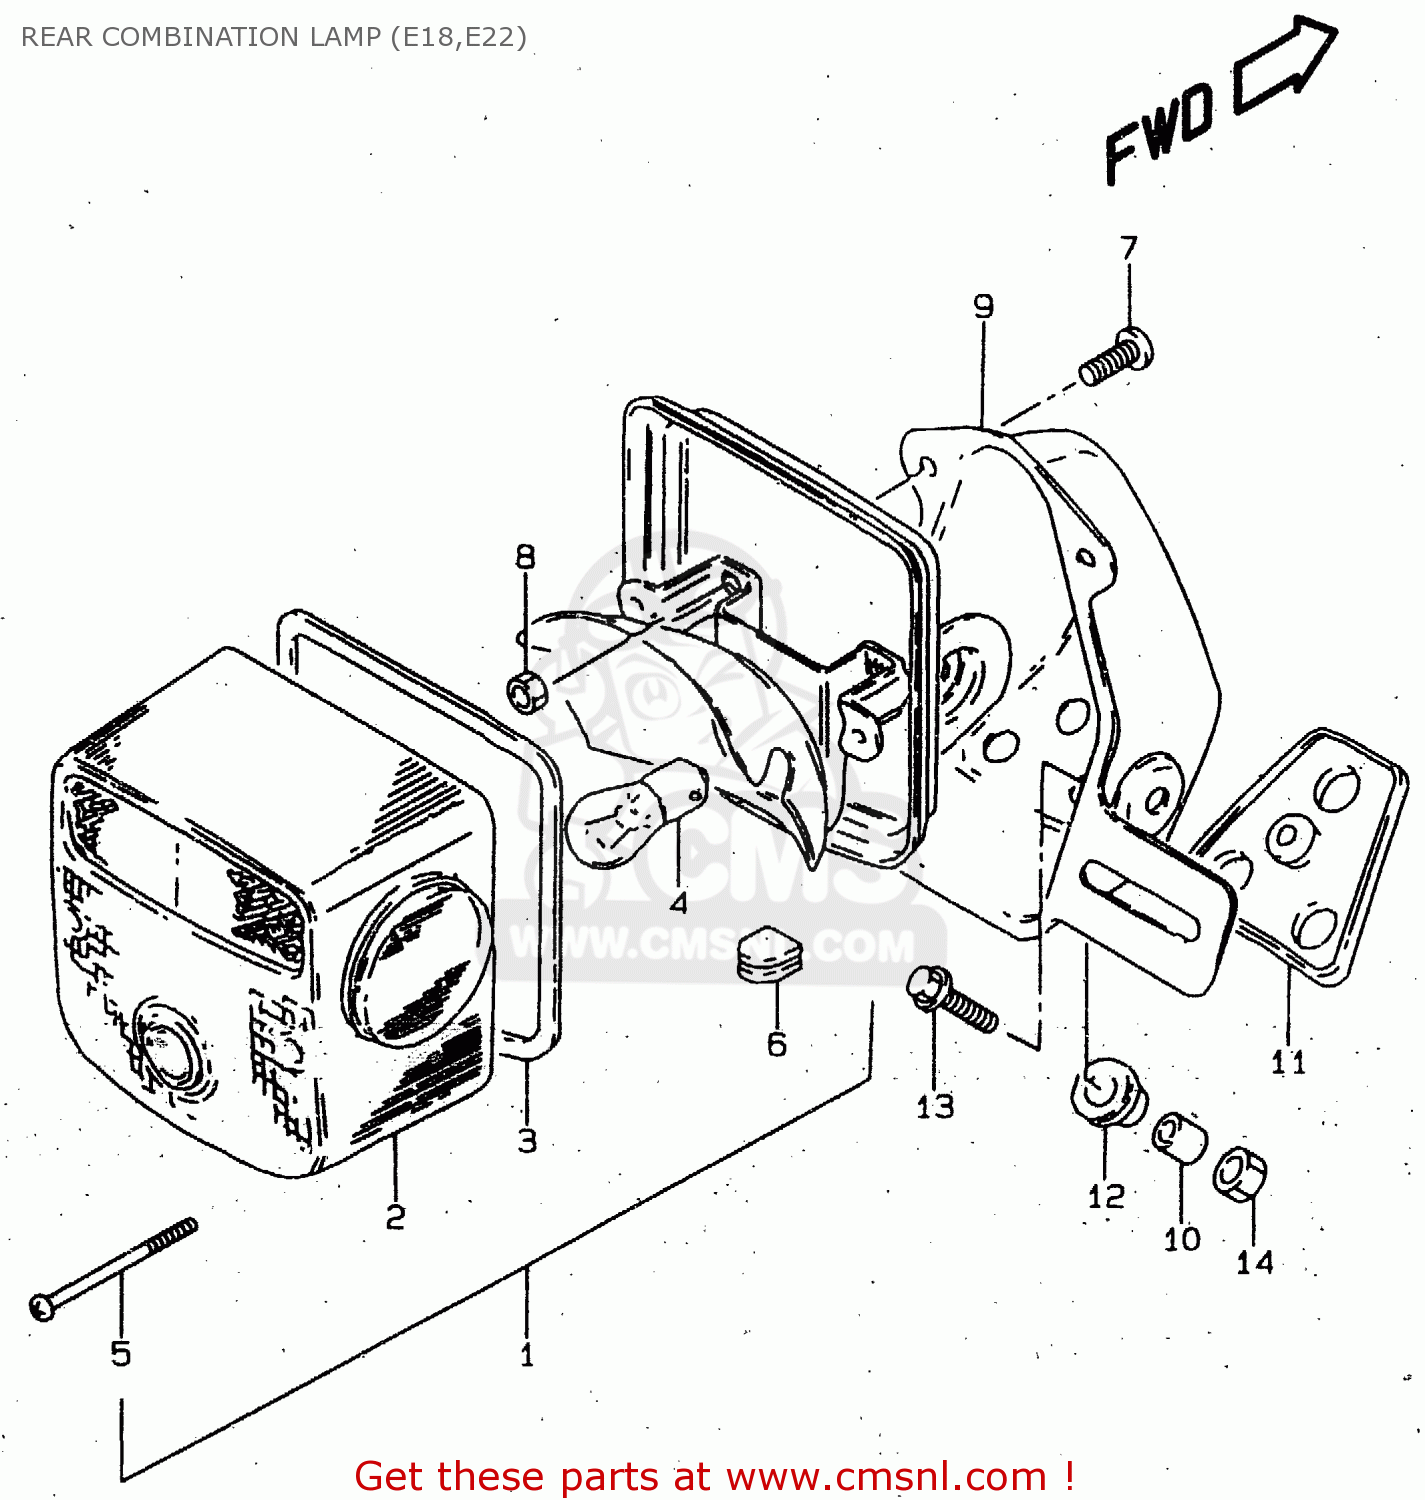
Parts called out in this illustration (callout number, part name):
1	LAMP ASSY,RR COMBINATION
2	LENS
3	GASKET (NAS)
4	BULB(12V21/5W)
5	SCREW (4X55)
6	GROMMET,REAR COMBINATION LAMP
7	SCREW
8	NUT
9	BRACKET UNIT,TAIL LAMP
10	SPACER
11	CUSHION
12	CUSHION
13	BOLT(6X20)
14	NUT 6MM
